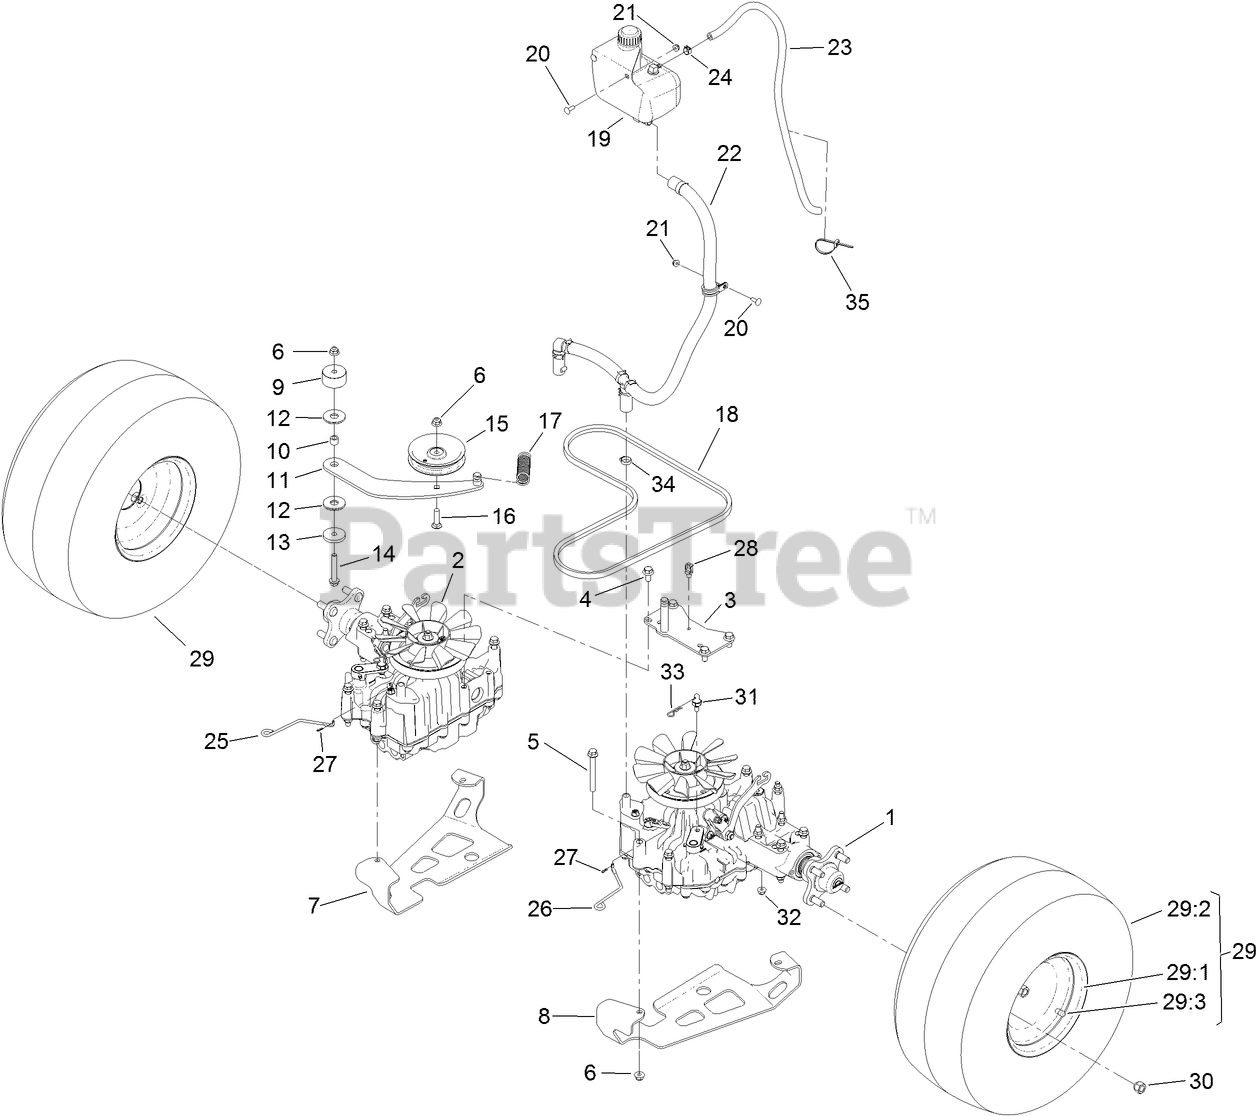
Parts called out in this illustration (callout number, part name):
1	TRANSAXLE-LH
2	TRANSAXLE-RH
3	SUPPORT-TRANSAXLE
4	SCREW-HHF
5	SCREW-HHF
6	NUT-HF, NI
7	PLATE-SKID, TRANSMISSION (RH)
8	PLATE-SKID, TRANSMISSION (LH)
9	SPACER
10	BUSHING-LEVER, LIFT
11	ARM-IDLER
12	WASHER-FRICTION, COMPOSITE
13	WASHER-PLAIN
14	SCREW-HHF
15	PULLEY-IDLER
16	SCREW-CARR
17	SPRING-EXTENSION
18	BELT-V
19	TANK-HYD
20	SCREW-CARR
21	NUT-HF
22	HYD HOSE ASM
23	HOSE-FUEL
24	CLAMP-HOSE
25	ROD-BYPASS, RH
26	ROD-BYPASS, LH
27	PIN-HAIR
28	CLIP-TIE
29	WHEEL AND TIRE ASM
29:1	RIM-8 INCH, GRAY
29:2	TIRE
29:3	STEM-VALVE
30	NUT-LUG
31	SPACER-HEX
32	NUT-HF, NI
33	PIN-COTTER
34	CLAMP-DRIVE, WORM
35	TIE-CABLE
